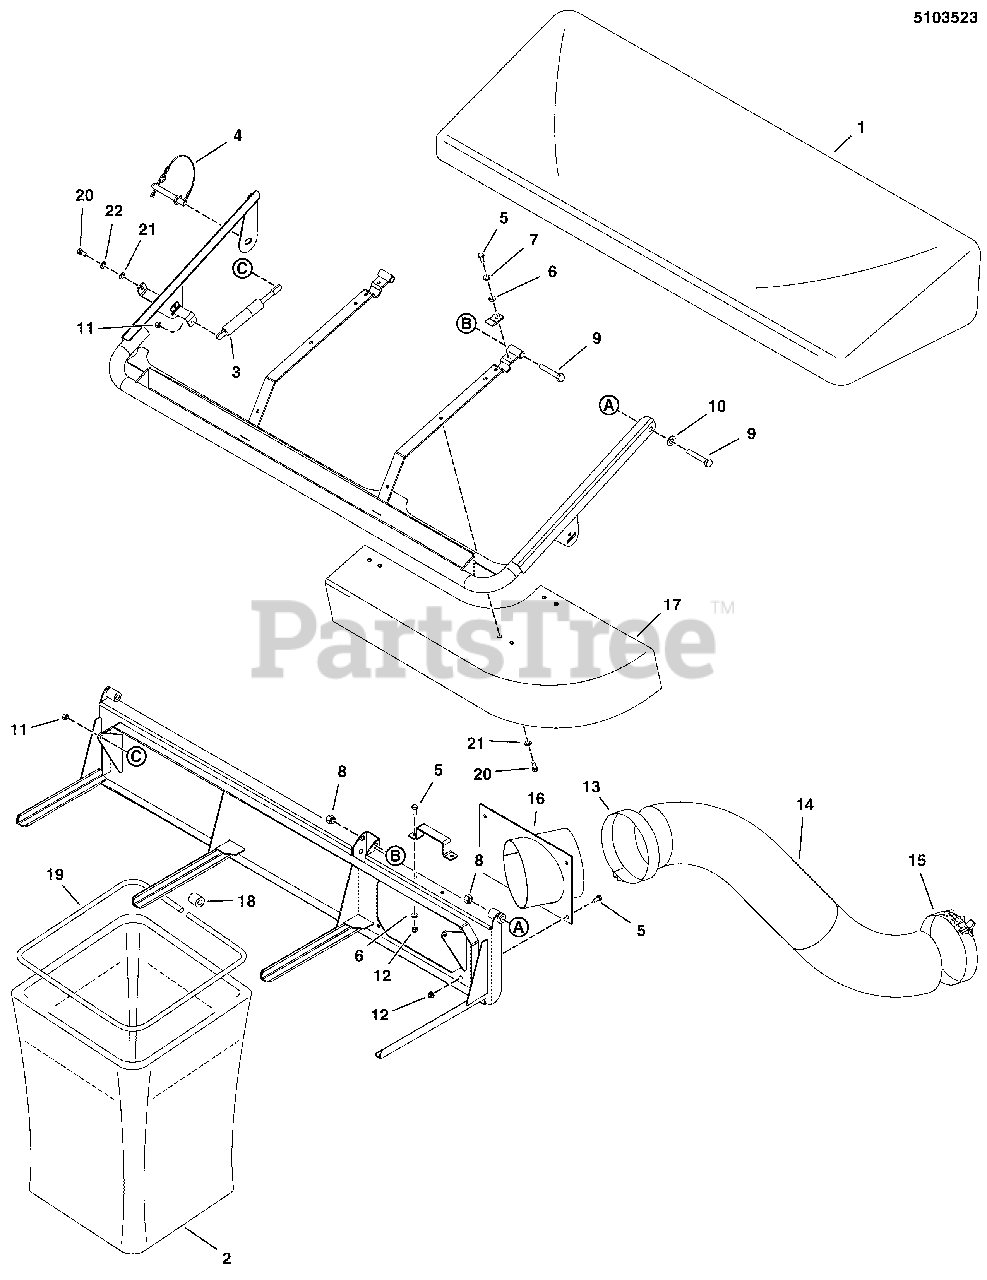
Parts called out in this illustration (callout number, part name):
1	3-BAG AIR DOME
2	CATCHER BAG W/ HANDLE
3	GAS CYLINDER
4	DETENT PIN W/ LANYARD
5	BOLT, 5/16-18 X 3/4 GD5
6	WASHER, 5/16" SAE
7	WASHER, 5/16 LOCK CZ
8	NUT, 1/2-13 HEX NYLON LOCK
9	BOLT, 1/2-20 X 3" GD5
10	WASHER, 1/2 SAE
11	NUT, 5/16-18 HEX NYLON LOCK
12	NUT, 5/16-18 HEX NYLOCK FLANGE
13	CLAMP, 6" UPPER & LOWER, COLLECTORS
14	HOSE, FLEXIBLE, 6" DIA X 54"
15	CLAMP, 6" LOWER, COLLECTORS
16	ASSM, BLWR INLET, 6.0, 3-BAG
17	WELD, DEFLECTOR - BLK
18	BAG FRAME CONNECTOR, PLASTIC
19	BAG FRAME
20	HHCS, 1/4-20 X 0.625, GR5, ZINC/CLEAR
21	WASHER, 1/4 SAE
22	WASHER, 1/4 LOCK
